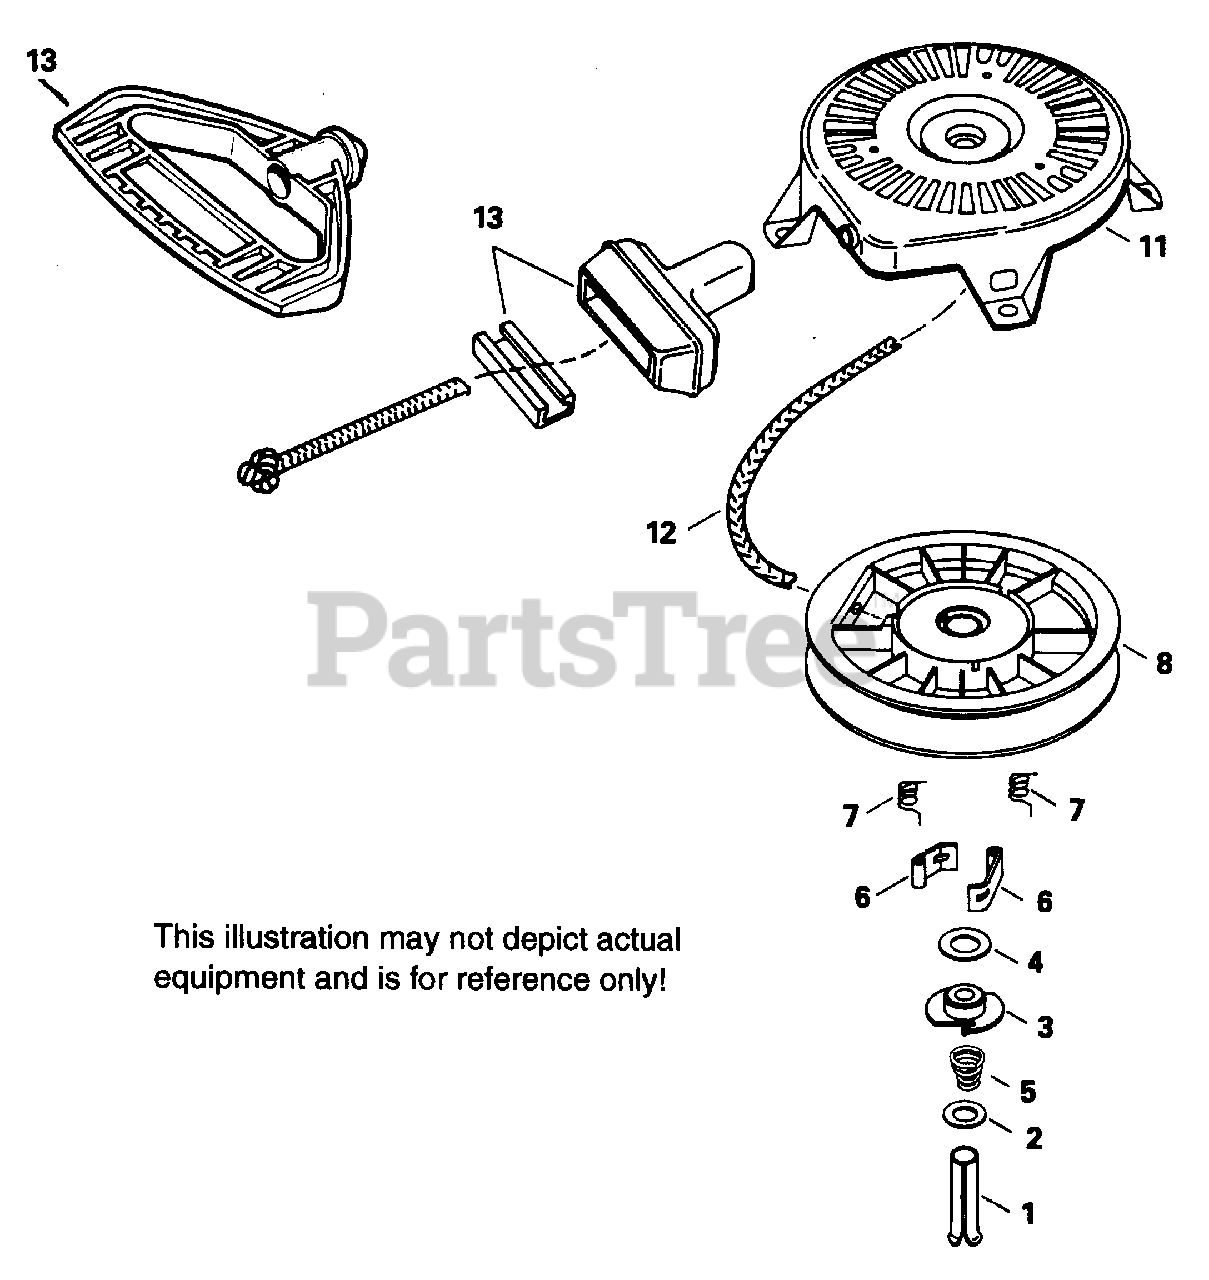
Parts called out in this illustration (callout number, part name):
1	Spring Pin (Incl. 4)
3	Retainer
5	Brake Spring
6	Starter Dog
7	Dog Spring
8	Pulley & Rewind Spring Ass'y.
11	Starter Housing Ass'y.
12	Starter Rope Length 114" x 11/64" dia .
13	Starter Handle
